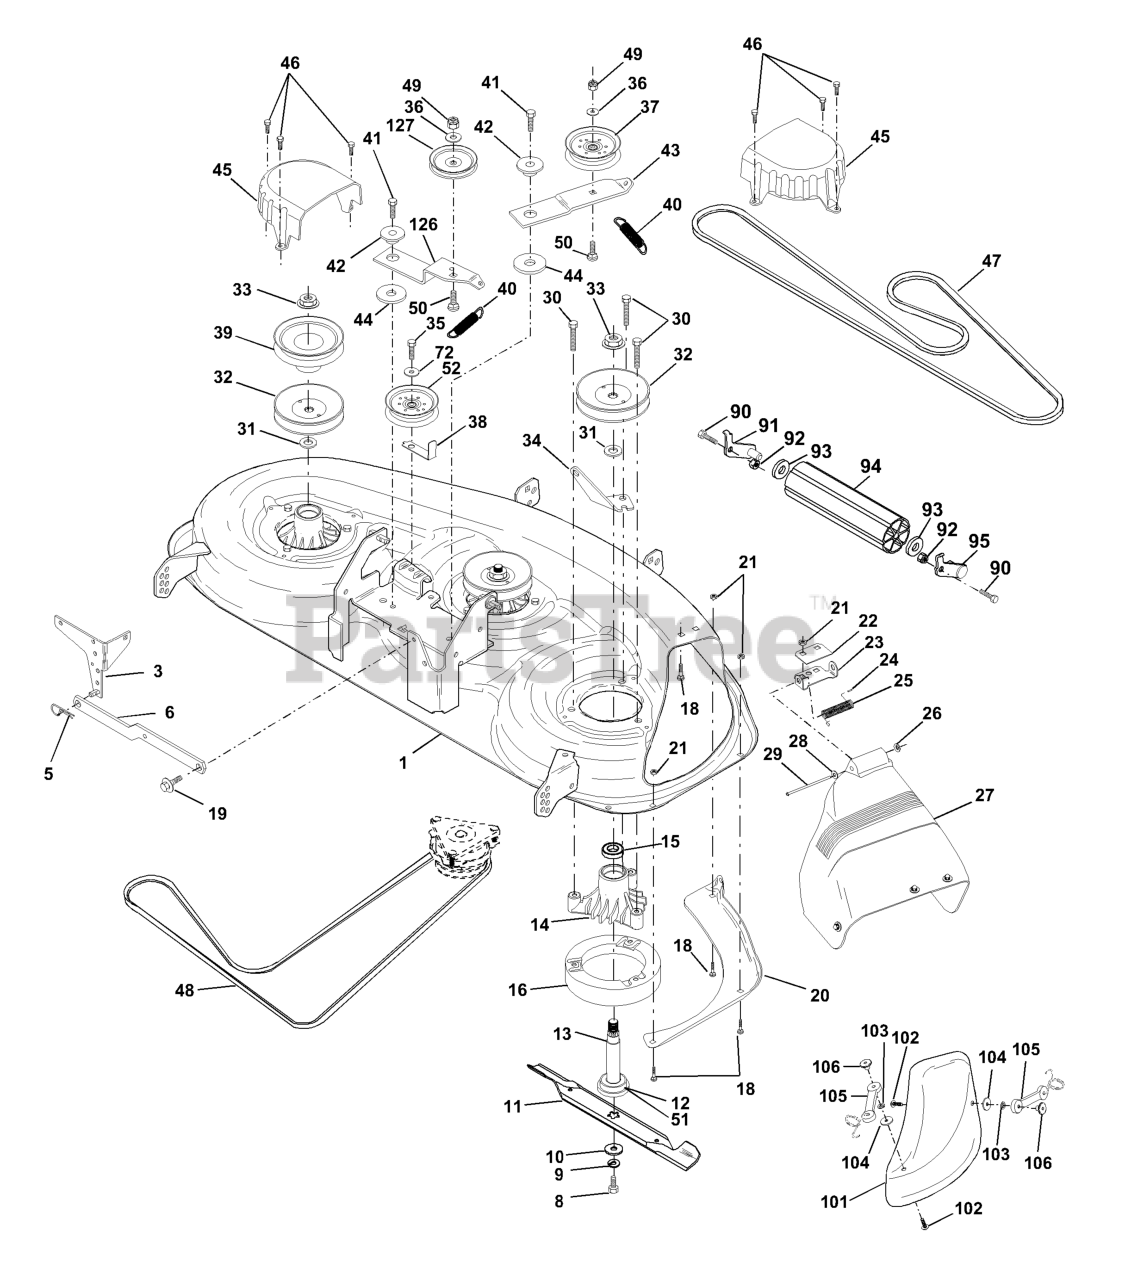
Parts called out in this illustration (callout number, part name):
1	DECK
3	BRACKET SWAY BAR
5	RETAINER-SPRNG RB
6	REAR SUSP ARM
8	BLADE BOLT
9	LOCKWASHER
10	WASHER.BLADE
11	46" HIGH PERFORMANCE BLADE
11	MULCH BLADE 46"
12	BEARING.BALL.#6204.(MANDREL)
13	SHAFT.ASM.W/BEARING
14	HOUSING.MANDREL.44/46" VENT
16	STRIPPER
18	BOLT
19	BOLT SHD 5/16-18
20	BAFFLE, VORTEX MOWER 46"
21	LOCKNUT
22	STIFFENER BRACKET
23	DEFLECTOR BRACKET
24	CAP-SLEEVE LT
25	TORSION SPRING
26	NUT PUSH M
27	SHIELD DEFLECTOR
28	Washer 11/32 x 5/8 x 16 Ga.
29	ROD.HINGE
30	SCREW THDROL ROLLING WASHER HD
31	CASE BATTERY
32	PULLEY, MANDREL
33	NUT
34	ANCHOR, SPRING DECK 46"
35	SCREW LT
36	WASHER
37	FLAT IDLER PULLEY
38	KEEPER.BELT.IDLER
39	PULLEY.DRIVEN.DECK.46"
40	SPRING.SEC.44"VEN
41	SCREW.3/8-16
42	SPACER.RETAINER.MOWER
43	ARM IDLER DECK 46"
44	HARDENED WASHER
45	COVER MANDREL 46
46	SCREW.1/4-20X5/8
47	BELT V SECONDARY
48	V-BELT PRIMARY 50"
50	BOLT.3/8-16X1.50
51	WASHER FELT
52	PULLEY IDLER FLAT 46 PRI DRIVE
56	BAR.ADJUST.WHEEL.ANTI.SCALP.BL
57	RIVET.PIN.HEAD.YELLOW.
72	WASHER
90	BOLT
91	BRACKET LH (A)
92	NUT
93	Washer 17/32 x 7/8 x 16 Ga.
94	NOSE ROLLER
95	BRACKET RH (B)
101	COVER.MULCH.46"3-BLADE.(2 2)
102	SCREW
103	LOCKWASHER #10
104	WELDNUT
106	LATCH ASSY
116	BOLT, SHOULDER
117	WHEEL GAGE DONUT
118	LOCKNUT
119	WASHER.5/16.FLAT.STE.STD.
126	ARM IDLER PRIM 46
127	PULLEY.IDLER.4.25
